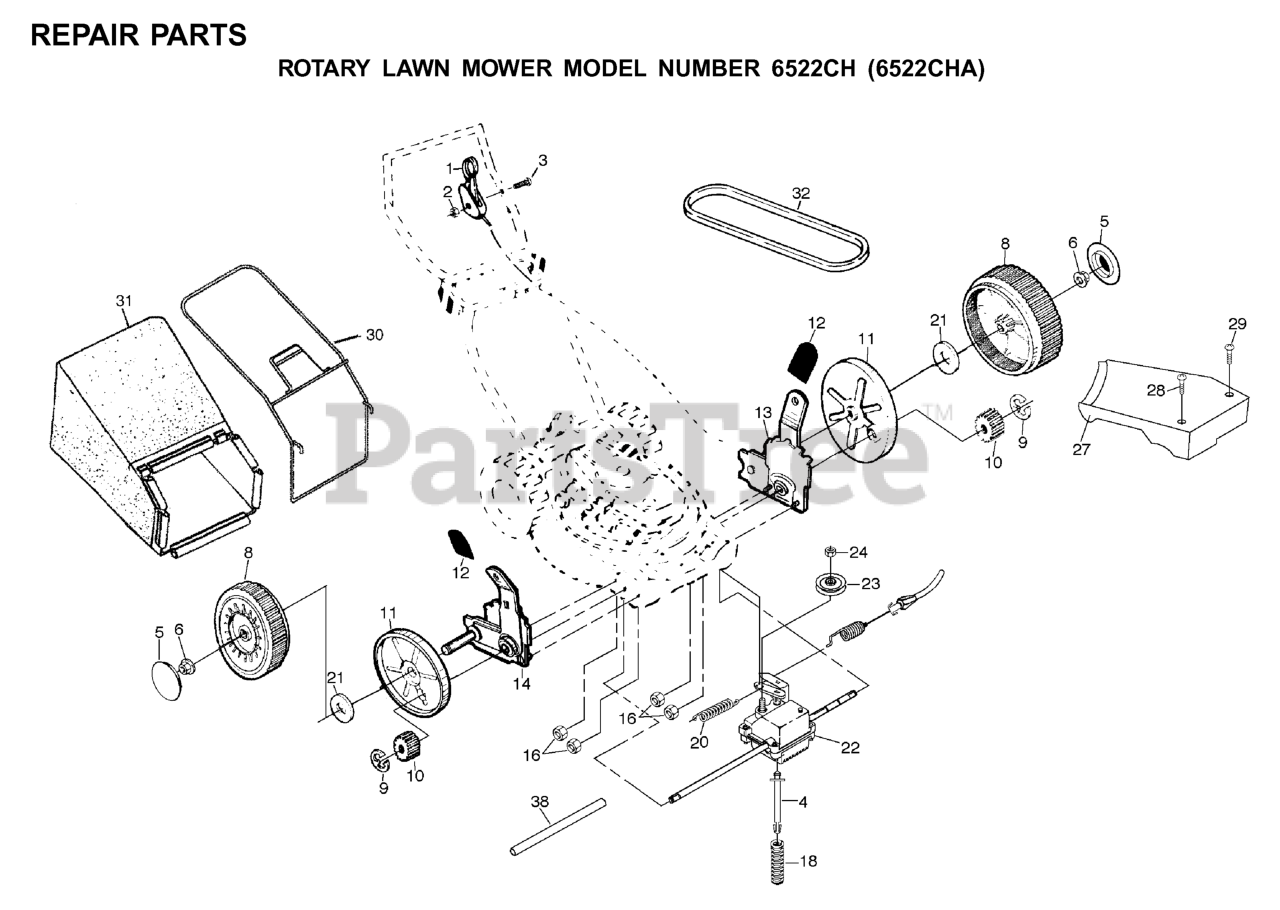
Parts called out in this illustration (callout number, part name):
1	DRIVE CONTROL
2	LOCK NUT
3	SCREW.PAN.HEAD
4	SPRING RETAINER
5	CAP.HUB.BLACK.WALK
6	NUT
8	WHEEL
9	E-RING 7/16 RE
10	PINION GEAR
11	DUST SHROUD PM
13	WHEEL ADJ ASM (L)
14	KIT.ADJUSTER.ASM.(151514).RT
16	NUT
18	SPRING.EXTENSION
21	WASHER FLUT
22	GEAR CASE ASMBLY
23	PULLEY
24	FLANGED LOCKNUT 3/8-16 ZINC
27	DRIVE COVER-GRAY
29	SCREW.SLOT.TORX.
30	CATCHER FRAME
32	BELT THERM .32
38	DRV SHAFT TUBE PM
